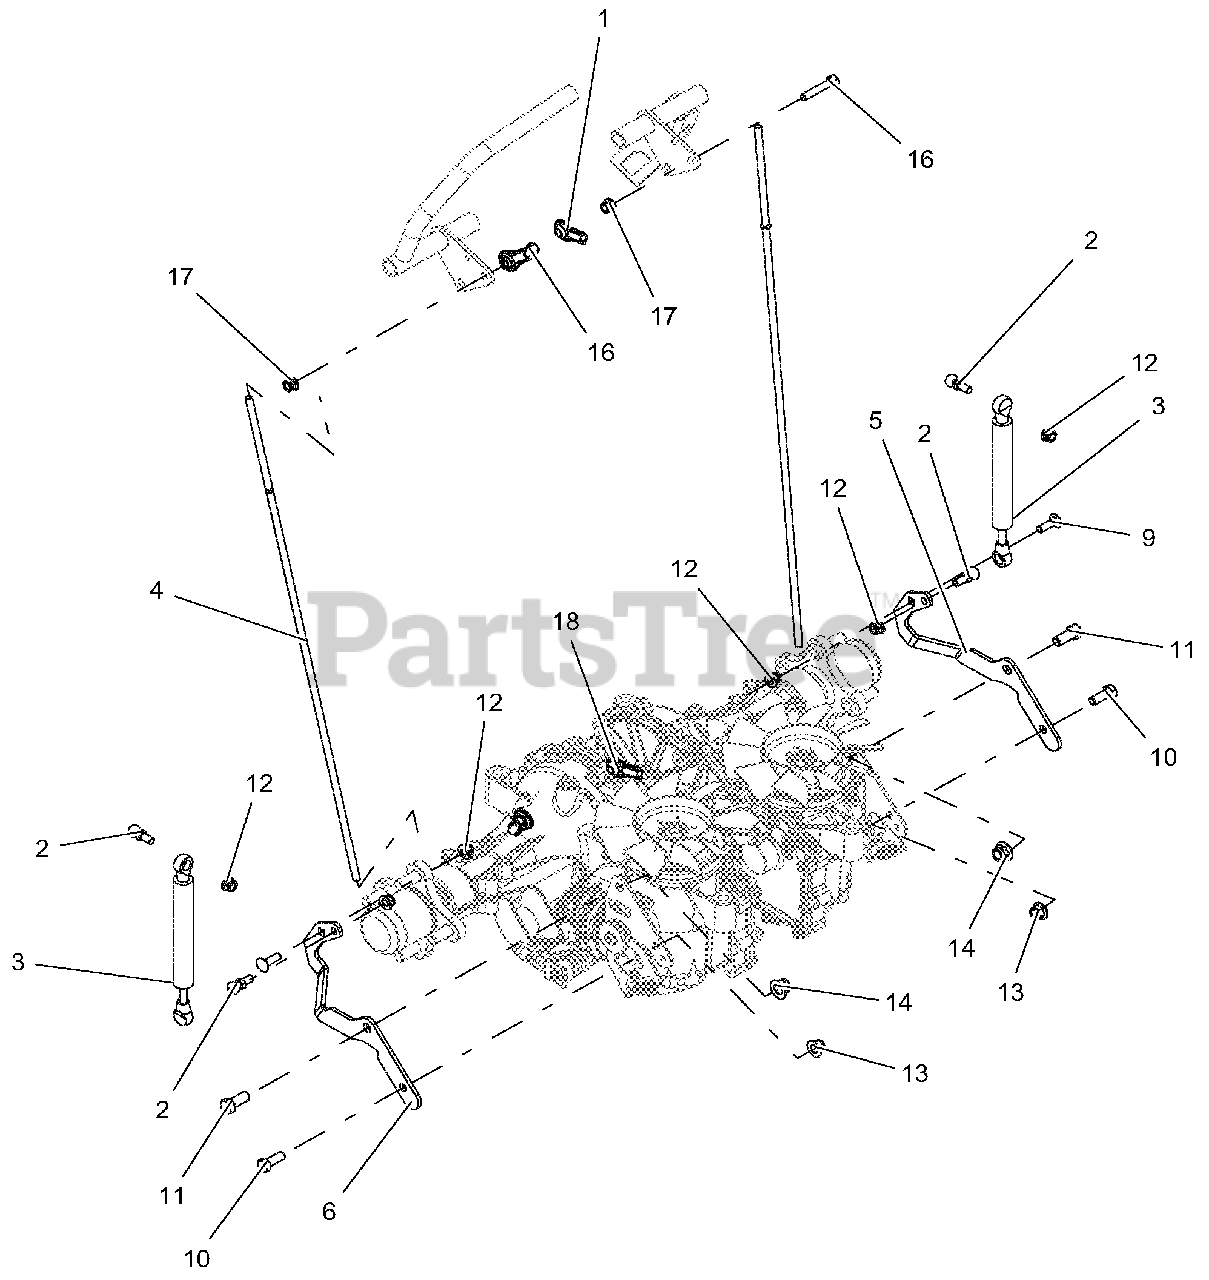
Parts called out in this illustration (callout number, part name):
1	ALIGNABALL, 5/16 LH THREAD
2	STUD-BALL
3	CONTROL DAMPER
4	ROD, STEERING
5	BRKT, LH TRANS CONTROL
6	BRKT, RH TRANS CONTROL
9	BLT-RDHDSQSHNK .31-18X1.00 G5 Y
10	BLT-HEX .38-16X1.00 GR5 YWZC
11	BLT-HEX .44-14X1.00 GR5 YWZC
12	NUT-LK-NYL-FLG .31-18 YWZC
13	NUT-LK-NYL-FLG .38-16 YWZC
14	NUT-LK-NYL-FLG .44-14 YWZC
16	BLT-HEX .31-18X1.75 GR5 YWZC
17	NUT-LK-NYL-FLG .31-18 YWZC
18	ALIGNABALL, 5/16 RH THREAD
